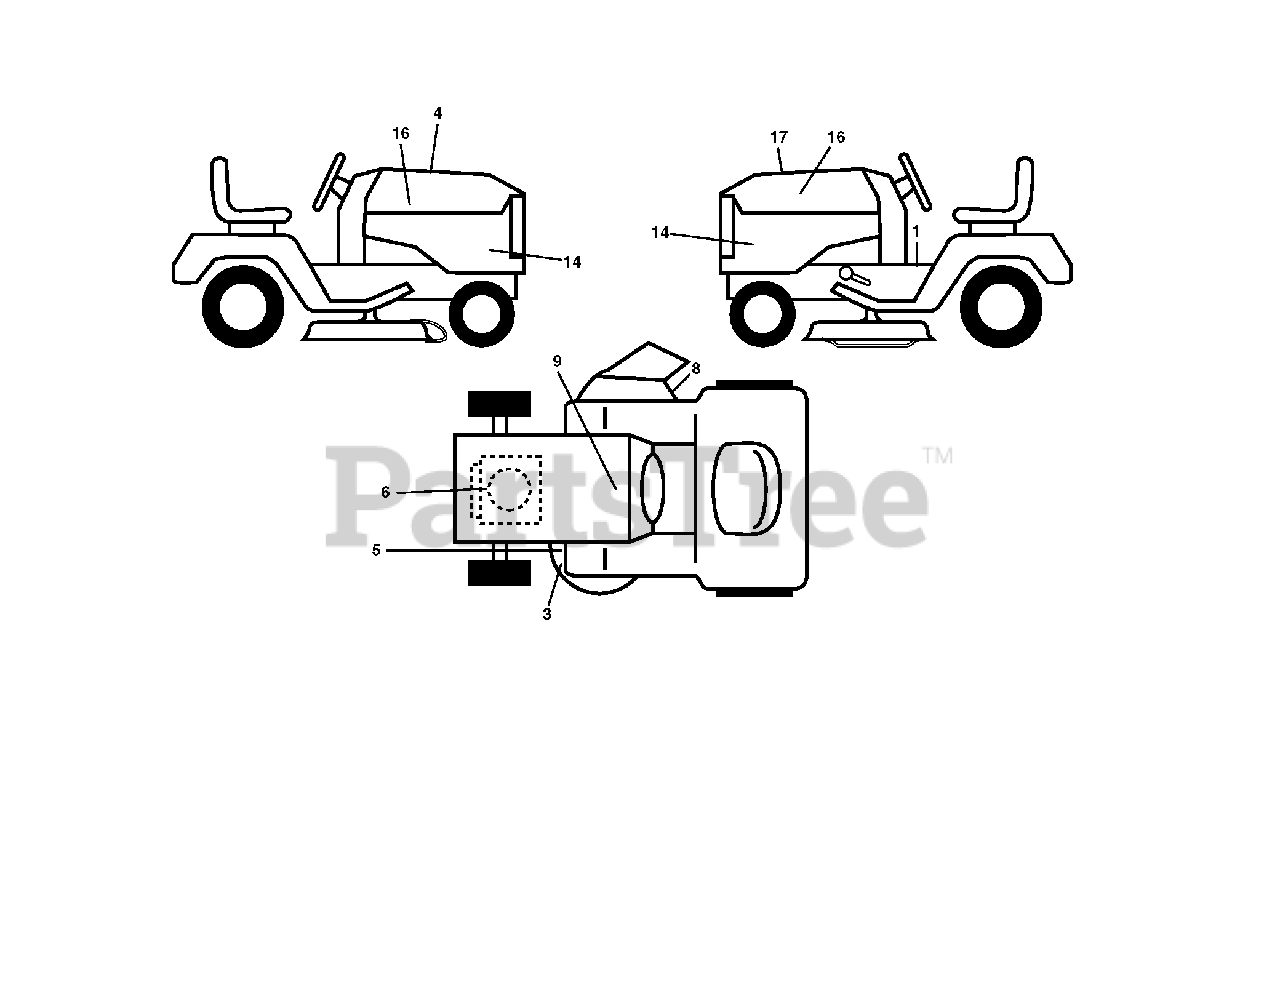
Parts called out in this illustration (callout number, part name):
1	DECAL.FENDER.WARNING.ENG
3	DECAL.WARN.KEEP.HAND.AWAY
4	DECAL.WARNING.CUST.RESP.E85.
5	DECAL.MOWER
6	Decal, Eng. HP
8	DECAL.MOWER.SCH.48/54
9	DECAL BTRY SYMBOLS
14	DECAL SDPNL.YTH24V54.B&S.HUSQ
16	RP.DECAL.BADGE.170MM.TEXTLOGO
17	Decal, Replacement
